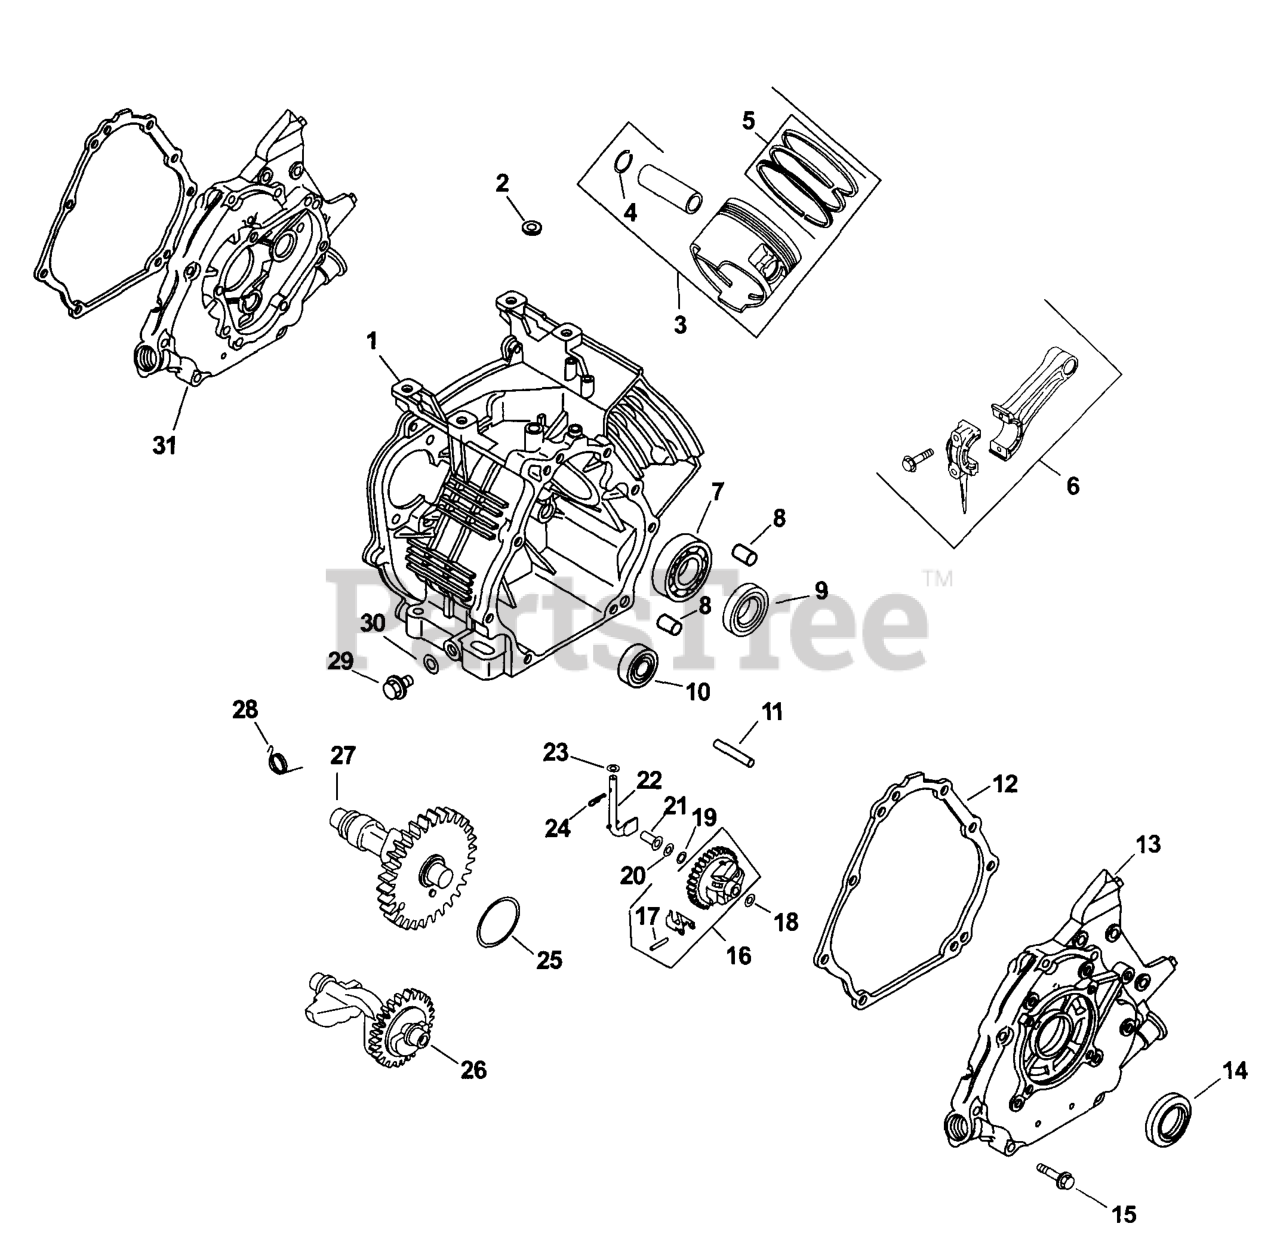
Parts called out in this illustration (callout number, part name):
1	- DISCONTINUED
2	SEAL, GOVERNOR CROSS SHAFT
3	PISTON W/RING SET (STD)
3	PISTON W/RING SET ( .25MM) - DISCONTINUED
3	PISTON W/RING SET (+.50MM)
4	RING, RETAINER
5	STANDARD RING SET
5	0.25MM RING SET
5	RING SET, 0.50
6	CONNECTING ROD
11	SHAFT, FLYWEIGHT
12	GASKET, C.P.
13	CLOSURE PLATE, G.R.
14	SEAL, FRONT OIL
15	SCREW, FLANGE
16	GOVERNOR GEAR ASSEMBLY
17	DOWEL PIN
19	SNAP RING
22	SHAFT, GOV CROSS
28	SPRING, ACR
29	PLUG, DRAIN
6321103-S	BOLT, CONN ROD
6375507-S	KIT, GASKET
